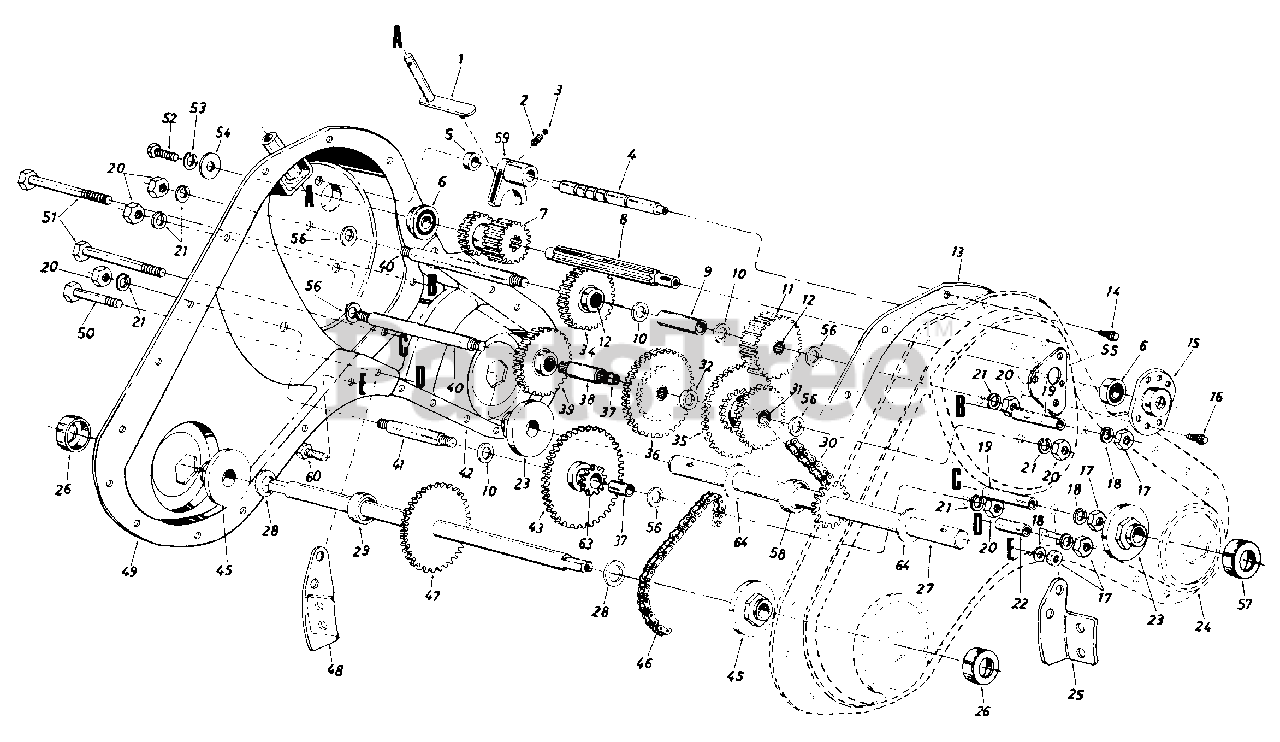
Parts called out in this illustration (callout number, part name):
1	Shifting Bracket Ass'y.
2	Compression Spring .50" Lg.
3	Ball Detent .250" Dia.
4	Detent Shaft 1/2" Dia.
5	Spacer .505" I.D. x .88" O.D.
6	Ball Brg. .62" I.D. x 1.38"
7	Spur Gear 16T
8	Input Spline Shaft 7/8"
9	Spacer .657" I.D. x 2.85" Lg.
10	Fl-Wash. .640" I.D. x 1.24"
11	Spur Gear 30T 7/8" I.D.
12	Needle Bearing 5/8" I.D.
13	Gasket Trans. Hsg.
14	Hex Wash. S-Tap Scr. 1/4-20 x.50" Lg.
15	1-3/8" Dia. Bearing Housing
16	Hex TT-Tap Scr. 1/4-20 x .75"
17	Hex Nut 5/16-18 Thd.
18	L-Wash. 5/16" I.D.
19	Spacer 1.56" Lg.
20	Hex Nut 7/16-20 Thd.
21	Bell-Wash. .45" I.D. x 1.0"
22	Spacer 1.015" Lg.
23	Tine Shaft Brg. 1.002 x 2.50
24	Trans. Housing Ass'y. L.H.
27	Tine Shaft Ass'y. 1" O.D.
28	Fl-Wash. .75" I.D. x 1.5" O.D.
29	Spacer .75" I.D. x .50" Lg.
30	Chain #50 5/8 Pitch x 52 Links Endless
31	Needle Bearing 5/8" I.D.
32	Fl-Wash. 5/8" I.D.
34	Spur Gear 30T 12/16" I.D.
35	30/44T Gear Ass'y. Comp.
36	Spur Gear 44T
37	Sleeve Bearing
38	Gear Hub 3/4" I.D. x 3" Lg.
39	Spur Gear 30T 1.0" I.D. x 1/2" W
40	Jack Shaft 5/8" Dia. x 5"
41	Jack Shaft 5/8" Dia. x 2.38"
45	Wheel Brg. .752" x 2.5"
46	#420 Chain 1/2 Pitch x 50 Links Endless
47	Wheel Shaft Ass'y. 15.6"
51	Hex Bolt 5/16-18 x 2.5"
52	Hex Bolt 1/4-20 x .62" Lg.
53	L-Wash. 3/8" I.D.
54	Fl-Wash. 1/4" I.D. x .93" O.D.
55	Gear Positioner Bracket
56	Fl-Wash. 7/16" I.D. x 1-3/8"
57	Dust Cover Ass'y. 1' Shaft
58	Spacer ln I.D. x 2" O.D.
59	Shifting Fork
60	Hex Bolt 5/16-18 x .75" Lg.
63	1QT Sprocket Ass'y.
64	Thrust Wash. 1.03" I.D. x 1 62" 0 D
